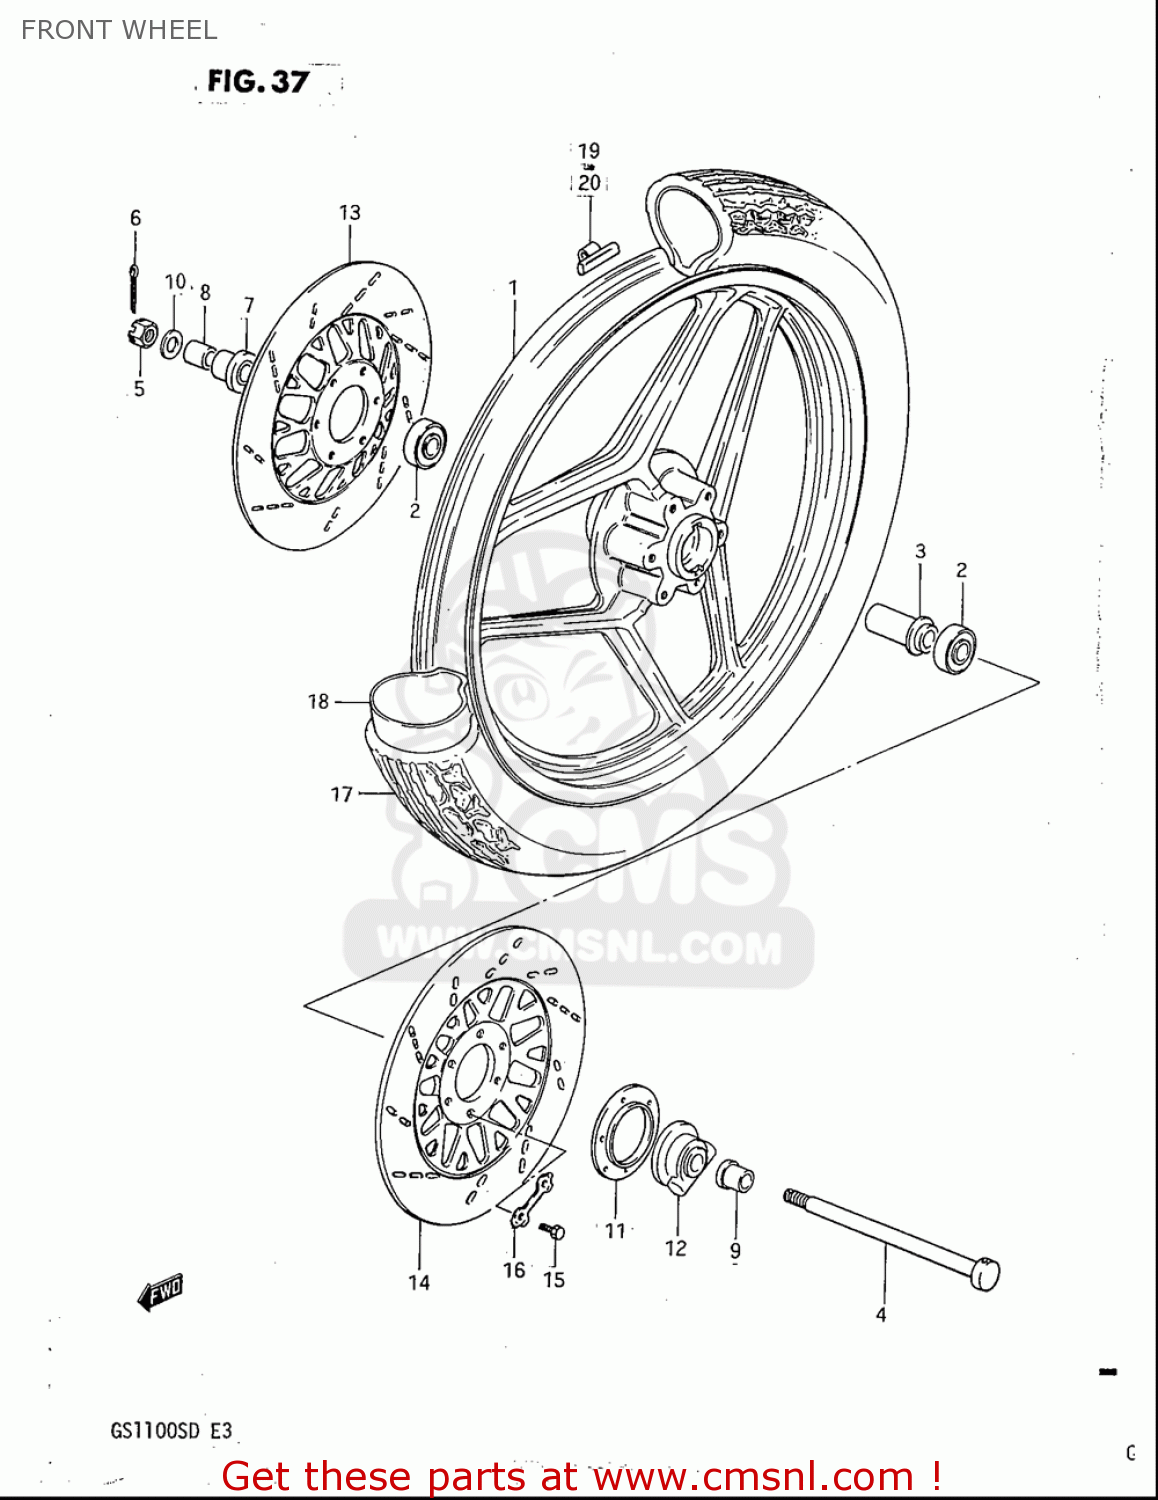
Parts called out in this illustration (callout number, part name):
3	SPACER,FR HUB BEARING
4	AXLE,FR
5	NUT 12MM
6	PIN
7	SPACER,FR AXLE,R
8	SPACER,FR AXLE,R
9	SPACER,FR AXLE,L
10	WASHER
11	DUST SEAL,SPEEDOMETER GEAR BOX
12	BOX ASSY,SPEEDOMETER GEAR
13	DISC,FR BRAKE,R
14	DISC,FR BRAKE,L
15	BOLT(8X25)
16	WASHER
18	TUBE ASSEMBLY,WHEEL,INNER
19	BALANCER,WHEEL(20G)
